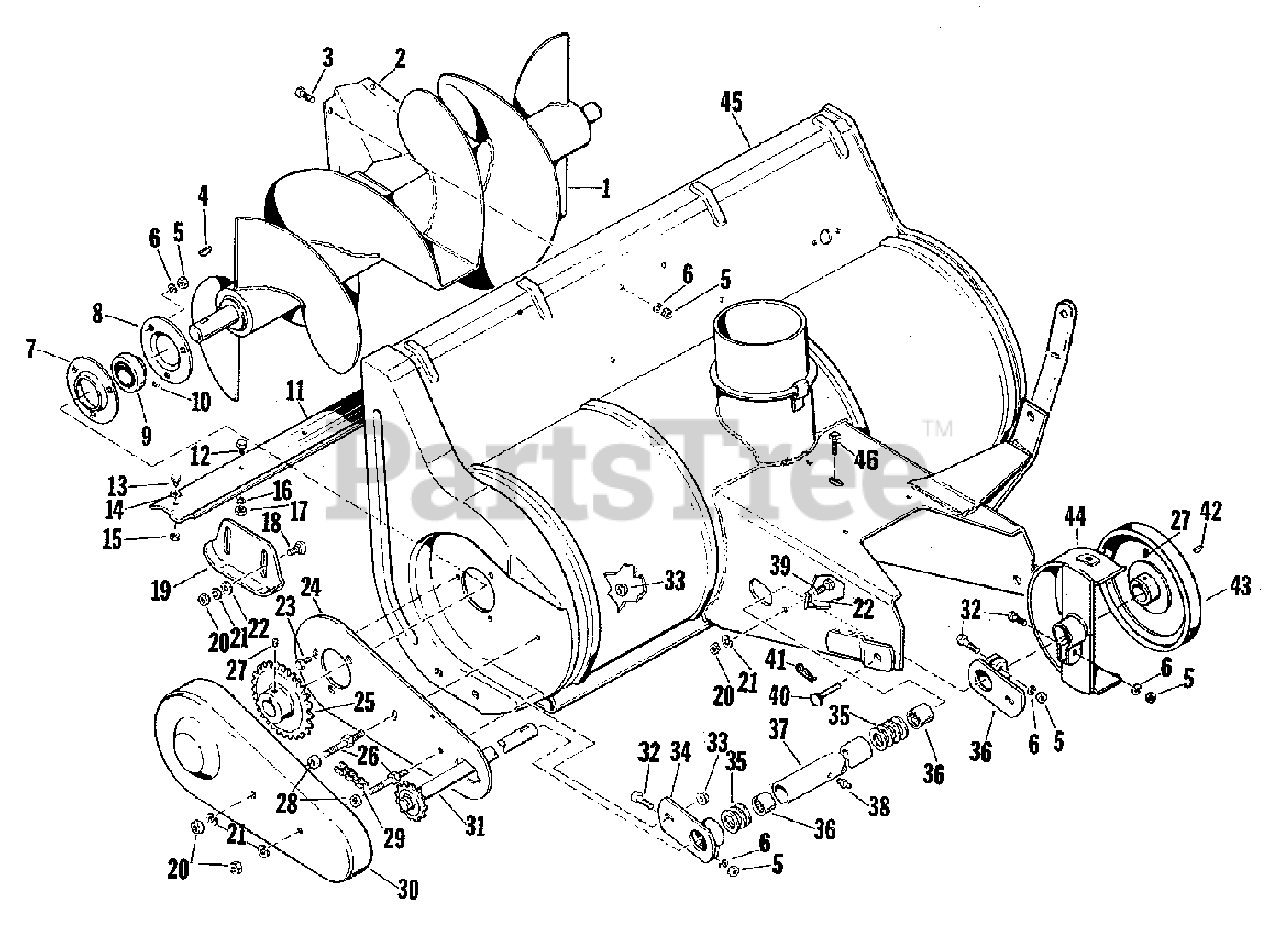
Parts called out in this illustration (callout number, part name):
1	ROTOR ASSEMBLY, 36"
1	ROTOR ASSEMBLY, 42"
3	SCREW, Hex Cap, 5/16-18 x 5/8
5	NUT, Hex, 5/16-18
6	WASHER, Lock, 5/16
7	FLANGE, Bearing
8	FLANGE, Bearing
9	BEARING, Cartridge
10	SCREW, Set, 1/4-28 x 1-4
11	SCRAPER, Body
12	SCREW, Hex Cap, 1/4-20 x 5/8
13	SCREW, Hex Cap, 5/16-18 x 5/8
14	WASHER, Flat, 1/4
15	NUT, Hex Lock, 5/16-18
16	WASHER, Lock, 1/4"
17	NUT, Hex, 1/4-20
18	BOLT, Carriage, 3/8-16 x 3/4
20	NUT, Hex, 3/8-16
21	WASHER, Lock, 3/8"
22	WASHER, Flat, 3/8"
23	SCREW, Hex Cap, 5/16-18 x 3/4
25	SPROCKET, Rotor
27	SCREW, Set, 5/16-18 x 5/16
28	NUT, Hex Lock, 3/8-16
29	CHAIN, With Connector Link
30	GUARD, Chain
31	SHAFT ASSEMBLY, 36"
31	SHAFT ASSEMBLY, 42"
32	SCREW, Hex Cap, 5/16-18 x 1-1/2
33	NUT, Flange "Whiz Lock" 3/8-16
34	SUPPORT ASSEMBLY, Clamp
35	WASHER, Flat
36	BEARING, Needle
37	HOUSING, Bearing
38	FITTING, Grease, 1/4-28
39	SCREW, Hex Cap, 3/8-16 x 1
40	PIN, Round Head, 3/8 x 2
42	KEY, Woodruff, #9
44	GUARD ASSEMBLY, Belt
45	BODY ASSEMBLY, 36"
45	BODY ASSEMBLY, 42"
46	SCREW, Cap, Taptite, 5/16-18 x 1/2
